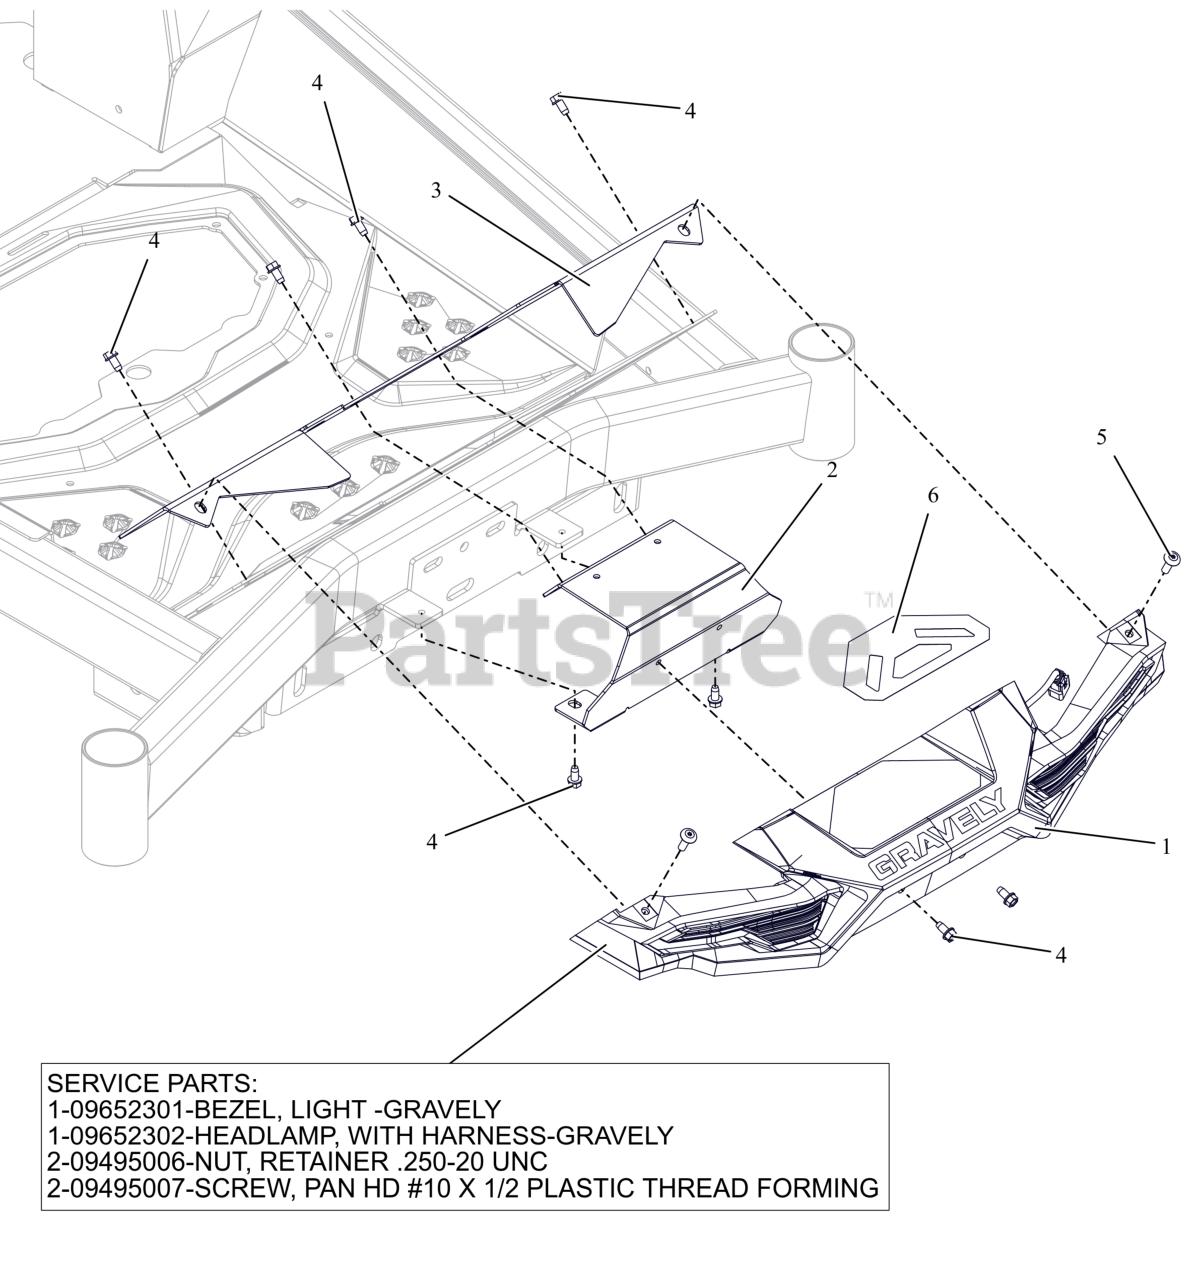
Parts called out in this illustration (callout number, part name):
1	LIGHT ASSY- HEADLIGHT GRAVELY
1	BEZEL LIGHT-GRAVELY
1	HEADLAMP- WITH HARNESS-GRAVELY
1	NUT, RETAINER .250-20 UNC
1	SCREW, PAN HD #10 X 1/2 PLACTIC THREAD FORMING
2	BRKT-FRT FACIA-LOWER-GRAVELY
3	BRKT- FRT FACIA UPPER-GRAVELY
4	SCR-TAP .25X.50 HWH ZB500
5	SCR-MCH .25-20X.75 TXTR ZB500
6	GRIP- TAPE-FRONT STEP-GRAVELY
